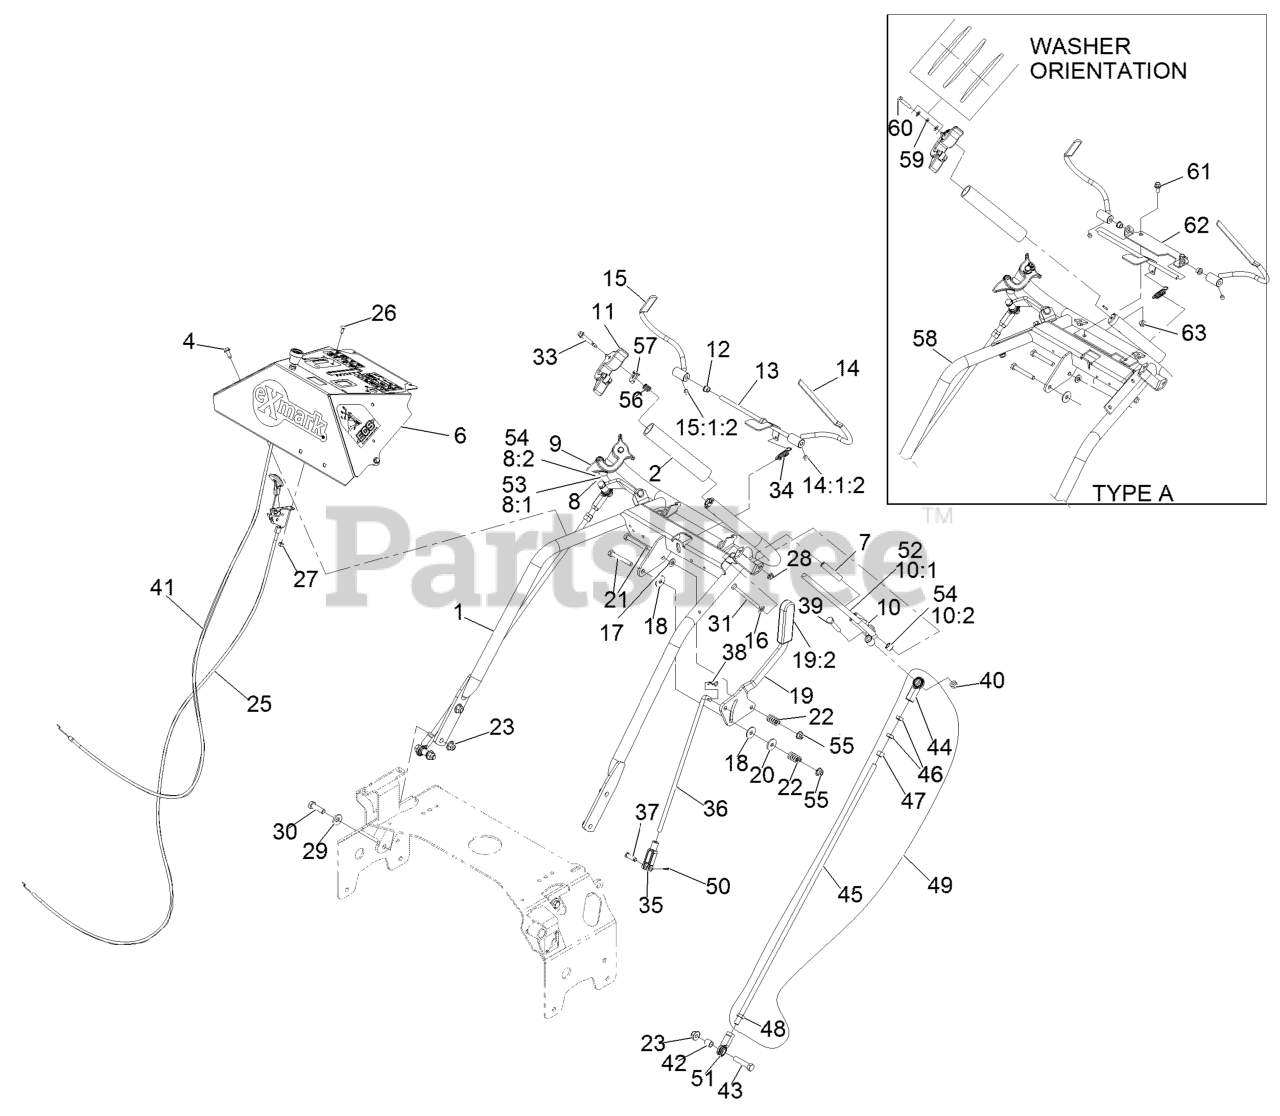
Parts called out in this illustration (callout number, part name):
1	WELD, HANDLE
2	GRIP-BAR, HANDLE
4	SCREW-HWH
6	ASM, CONSOLE W/ DECALS
7	BUSHING-LEVER, DRIVE
8	DRIVE LEVER-ASM, RH
8:1	WLD,RH DRIVE LEVER
8:2	BUSHING-SLEEVE
9	ASM,LATCH RH THUMB
10	DRIVE LEVER-ASM, LH
10:1	WLD,LH DRIVE LEVER
10:2	BUSHING-SLEEVE
11	ASM,LATCH LH THUMB
12	BUSHING-NYLON
13	WLD,OPC LEVER AXLE
14	WLD,LH OPC LEVER
14:1:2	SCREW-SET
15	WLD,RH OPC LEVER
15:1:2	SCREW-SET
16	WASHER-FLAT
17	WASHER-PLAIN
18	WASHER-FRICTION
19	LEVER, SHIFT W/GRIP
19:2	GRIP-HANDLE, STEERING
20	WASHER-FRICTION
21	SCREW-HH
22	SPRING-COMPRESSION
23	NUT-HF, NI
25	CONTROL-THROTTLE
26	BOLT-CARR
27	NUT-LOCK, NI
29	WASHER-BELLEVILLE
30	SCREW-HH
31	SCREW-HH
33	SCREW-SHOULDER
34	SPRING-EXTENSION
35	YOKE-ADJUSTABLE
36	ROD,SPEED CONTROL
37	PIN-CLEVIS
38	PIN-COTTER
39	SCREW-HH
40	NUT-LOCK, NI
41	CABLE, CHOKE
42	SPACER-TUBE, PUMP LINK
43	SCREW-HH
44	JOINT-BALL, END
45	LINK,DRIVE (PLTD)
46	NUT-HJ
47	NUT-HEX
48	NUT-HEX JAM, LH
49	DRIVE LINK ASM
50	PIN-COTTER
51	JOINT-BALL END, LH
52	WLD,LH DRIVE LEVER
53	WLD,RH DRIVE LEVER
54	BUSHING-SLEEVE
55	NUT-HF, NI
56	SPRING-TANK, FUEL
57	LATCH, ECS
58	WLD,TTH ECS HANDLE
59	WASHER-SPRING
60	SCREW-HH
61	SCREW-HEAD, FLANGE
62	BRACKET,OPC AXLE
